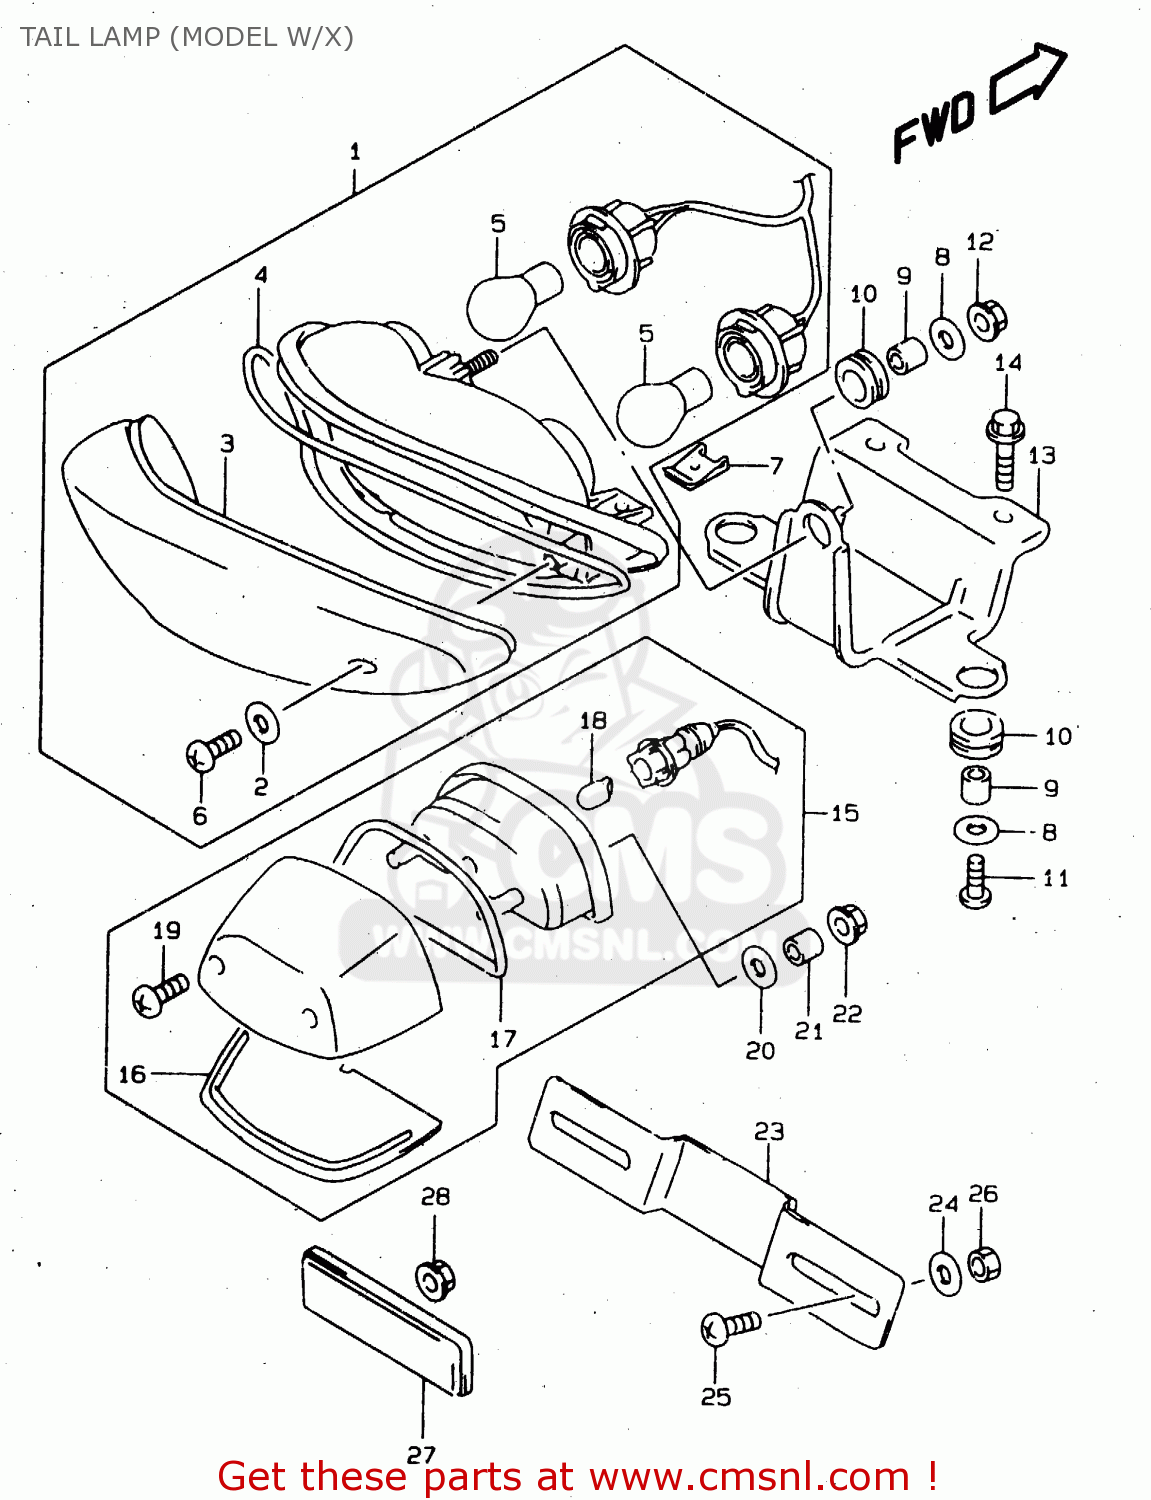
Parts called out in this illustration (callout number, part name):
1	LAMP ASSY,RR COMBINATION
2	GASKET (NAS)
3	LENS
4	GASKET (NAS)
5	BULB(12V21/5W)
6	SCREW
7	NUT
8	WASHER(6.5X20X1.6)
9	SPACER(6.5X10X9)
10	CUSHION
11	SCREW
12	NUT
13	BRACKET,RR COMBINATION LAMP
14	BOLT
15	LAMP ASSY,LICENSE
16	LENS
17	GASKET (NAS)
18	BULB(12V5W)
19	SCREW
20	WASHER(6.5X20X1.6)
21	SPACER(5.5X9.5X11.5)
22	NUT
23	BRACKET,LICENSE PLATE
24	WASHER(6.5X20X1.6)
25	SCREW 6X12
26	NUT
27	REFLECTOR ASSEMBLY,REAR
28	NUT
